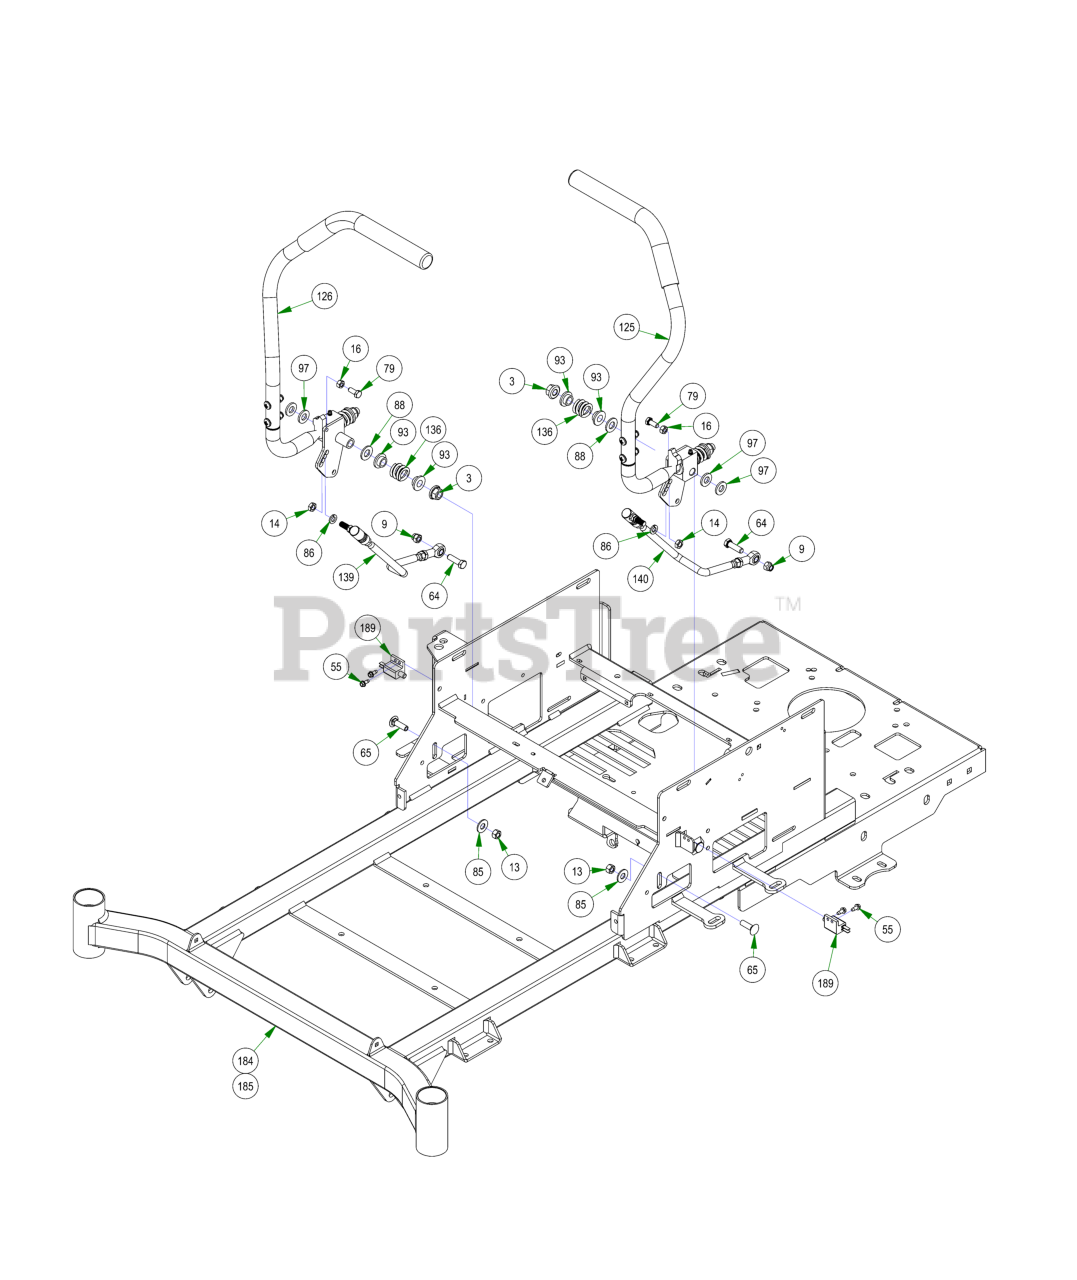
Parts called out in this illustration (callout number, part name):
3	1/2-13 HEX FLANGE AUTO OVAL LOCKNUT (GR.F) ZINC/WAX
9	3/8-16 NYLON INSERT LOCKNUT ZINC
13	3/8-16 HEX NUT ZINC
14	3/8-24 HEX NUT ZINC YELLOW
16	5/16-18 HEX NUT ZINC
55	12-24 X 1/2 HEX WASHER UNLSOT F TCS ZINC
64	3/8-16 X 1-1/4 HEX CAP SCREW (GR.5) ZINC
65	3/8-16 X 1-1/4 CARRIAGE BOLT ZINC
79	5/16-18 X 3/4 HEX CAP SCREW (GR.5) ZINC
85	3/8 FLAT WASHER USS (1" OD) ZINC
86	3/8 SPLIT LOCKWASHER ZINC
88	1/2 SAE FLAT WASHER (1-1/16" OD) GR.8 ZINC YELLOW
93	.525 ID SHOULDER WASHER NYLON
97	.505 ID X 1.000 OD X .125 THICK FLAT WASHER NYLON
125	2017 MZ Magnum LH Steering Arm
126	2017 MZ Magnum RH Steering Arm
136	Drive Lever Spring
139	Push Rod-Right
140	Push Rod-Left
184	2023 MZ 42-48 Frame - Painted
185	2023 MZ-Avenger 54-60 Frame - Painted
189	Safety Switch
